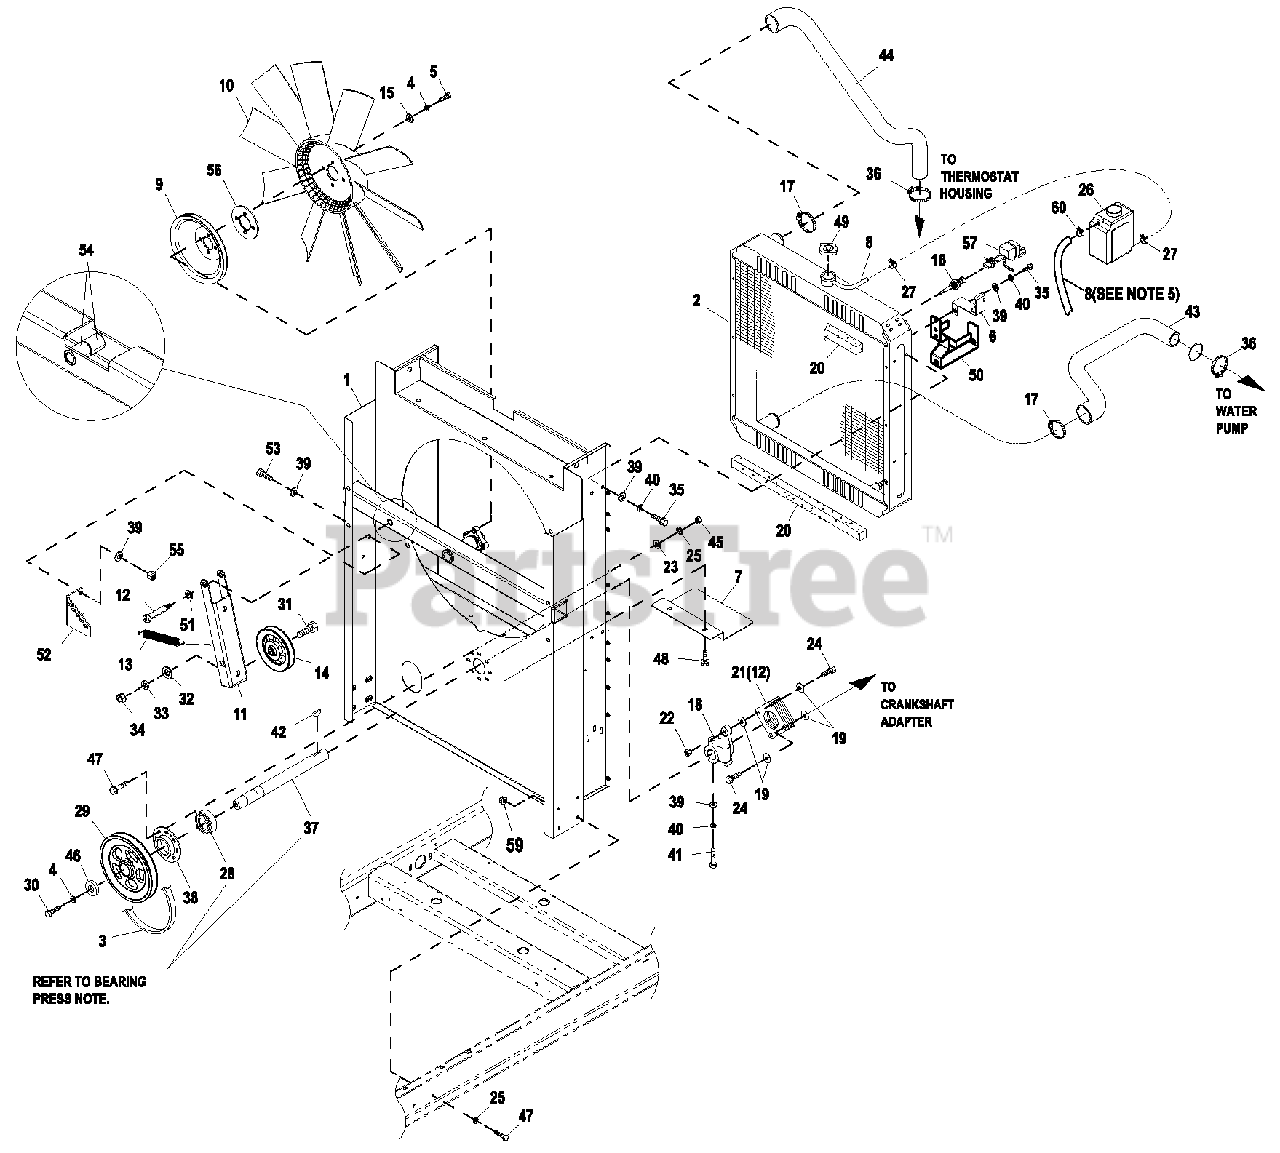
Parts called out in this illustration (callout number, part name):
1	NIPPLE CLOSE 3/4X1.375
2	FLANGE FUEL INLET
3	REGULATOR ASSY 2.4L (25KW)
4	SCREW HHC M8-1.25X20 G8.8
5	WASHER FLAT 5/16-M8 ZINC
6	WASHER LOCK M8-5/16
7	NUT HEX M8-1.25 G8 CLEAR ZINC
9	STREET EL 45D 1/2 NPT BRASS
10	ELBOW 90D 3/4 NPT
11	NIPPLE PIPE 3/4 NPT X 3-1/2
13	CLAMP HOSE #10.56-1.06
14	HOSE 3/4 ID SAE-30R2 (18" LG)
15	BARBED STR 1/2 NPT X 3/4
18	O-RING 45.63 ID X 2.62 WIDTH
19	GASKET BOSCH 32
20	ACTUATOR BOSCH 40 GOVERNOR (45KW)
21	HOSE COOLING 2IN ID 20R4 (2IN) (45KW)
22	MIXER ACTUATOR 32MM MACHINED (25KW)
23	VENTURI THROTTLE 26MM (35 & 45KW)
24	O-RING 47.625 ID X 2.38 WIDTH
26	WASHER LOCK M6-1/4
27	SCREW SHC M6-1.0 X 45 G12.9
28	CLAMP HOSE #28 1.32-2.25
29	HARNESS CPL FUEL JUMPER
30	HOSE 3/8 ID SINGLE BRAID (18" LG)
32	CLAMP HOSE #10.56-1.06
33	REDUCING TEE, 3/4 X 1/4 X 3/4
34	PLUG, PRESSURE GAUGE, 1/4" NPT
35	HANG TAG FUEL PRESS TEST POINT
36	TIE WRAP UL 5.6 X.10 BLACK
37	PLUG PLASTIC 0.75" TAPERED CAP
